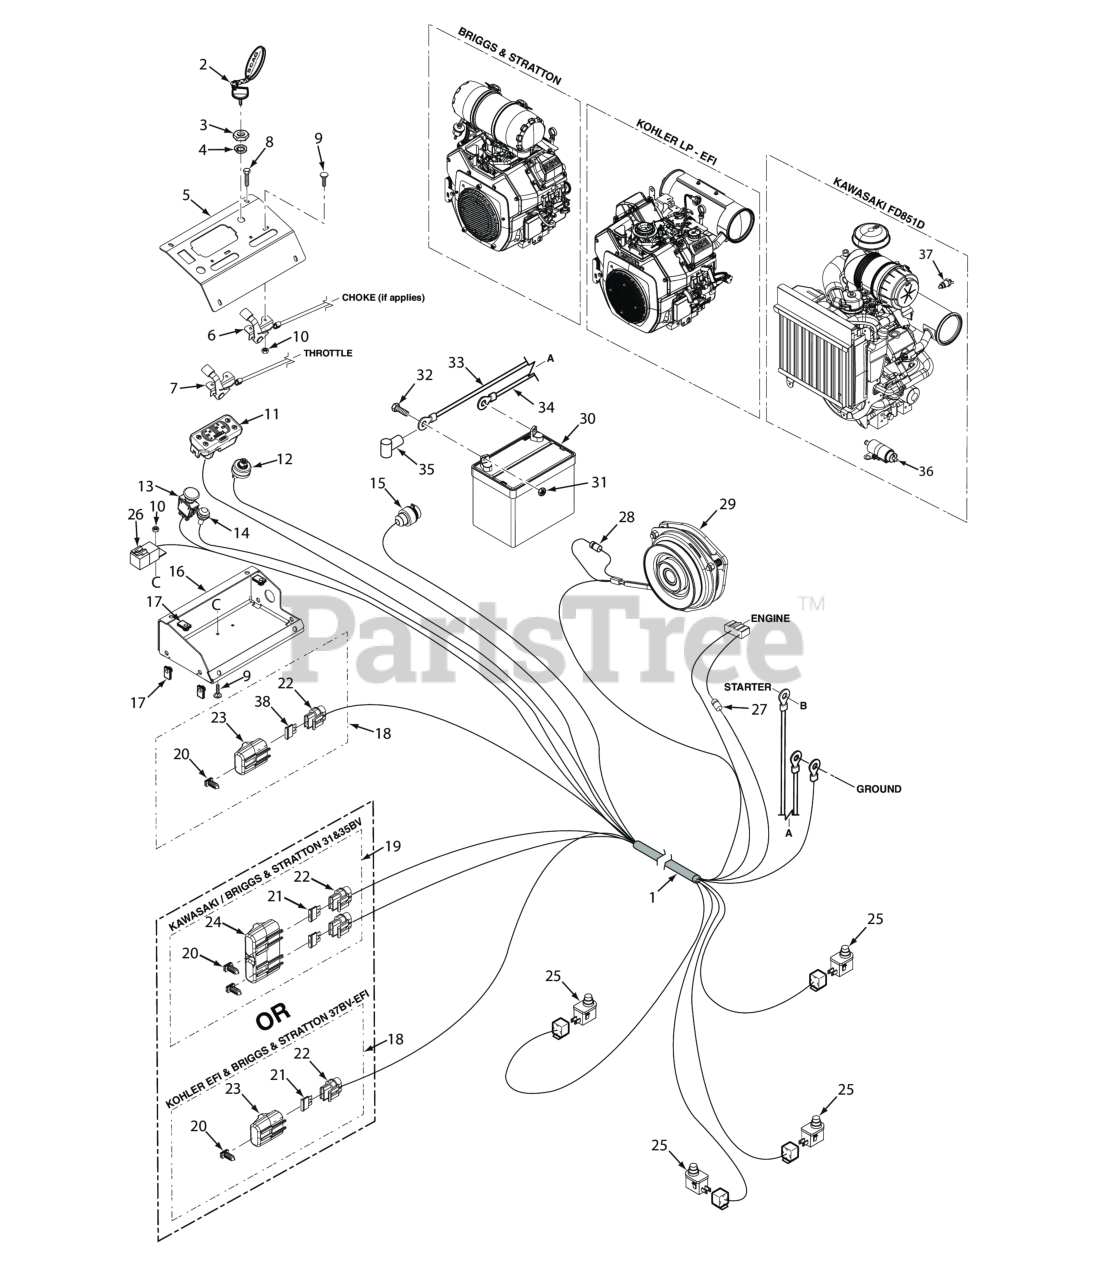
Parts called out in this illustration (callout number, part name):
1	Wire Harness, STTII-BV (Briggs & Stratton)
2	Key, Assembly w/Fob
3	Nut, 5/8-32 Special
4	LOCK WASHER, 5/8" INTERNAL TOOTH
5	Instrument Panel w/Decal
6	Control Cable (Kawasaki FX921 Throttle & Choke Cable)
7	Control Cable (Briggs & Stratton)
8	Bolt, Hex Head Serrated Flange 1/4-20 x 3/4"
9	Bolt, Carriage #10-24 x 1/2"
10	Nut, Elastic Stop #10-24
11	Tiger Eye, Cluster Gauge
12	KEY SWITCH(INCLUDES MOUNTING HARDWARE)
13	Switch, PTO - 10 Amp
14	Indicator Light, Glow Plugs (Includes Mounting Hardware)
15	Power Plug, 12V
16	Base, Instrument Panel
17	Bolt, Hex Head 3/8-16 x 1"
18	Single Fuse Assy., Excluding Fuse
19	Double Fuse Assy.
20	Clip, Fuse Holder
21	FUSE, 20 AMP BLADE TYPE AUTOMOTIVE
22	Fuse Holder Assembly
23	Cover, Sealed Single
24	Cover, Sealed Double
25	Switch, Interlock, Normally Open
26	Relay, 12V 40 AMP Standard
27	Decal, Forward Speed Selector
28	Diode, 600V 6 Amp
29	Electric Clutch w/Tag - GT-3.5 (FX850)
30	Battery, 350 CCA
31	Nut, 1/4 - 20 Hex
32	Bolt, Hex Head 1/4-20 x .5" Battery, (Not Available Through Scag)
33	Battery Cable, 44" Red w/Braid (26EFI) - Kohler
34	Battery Cable, 39" Black (26EFI) - Kohler
35	RUBBER BOOT
36	Fuel Pump
37	Sender Unit, Water Temp. (Liquid Cooled Only)
38	Fuse, 5 Amp
